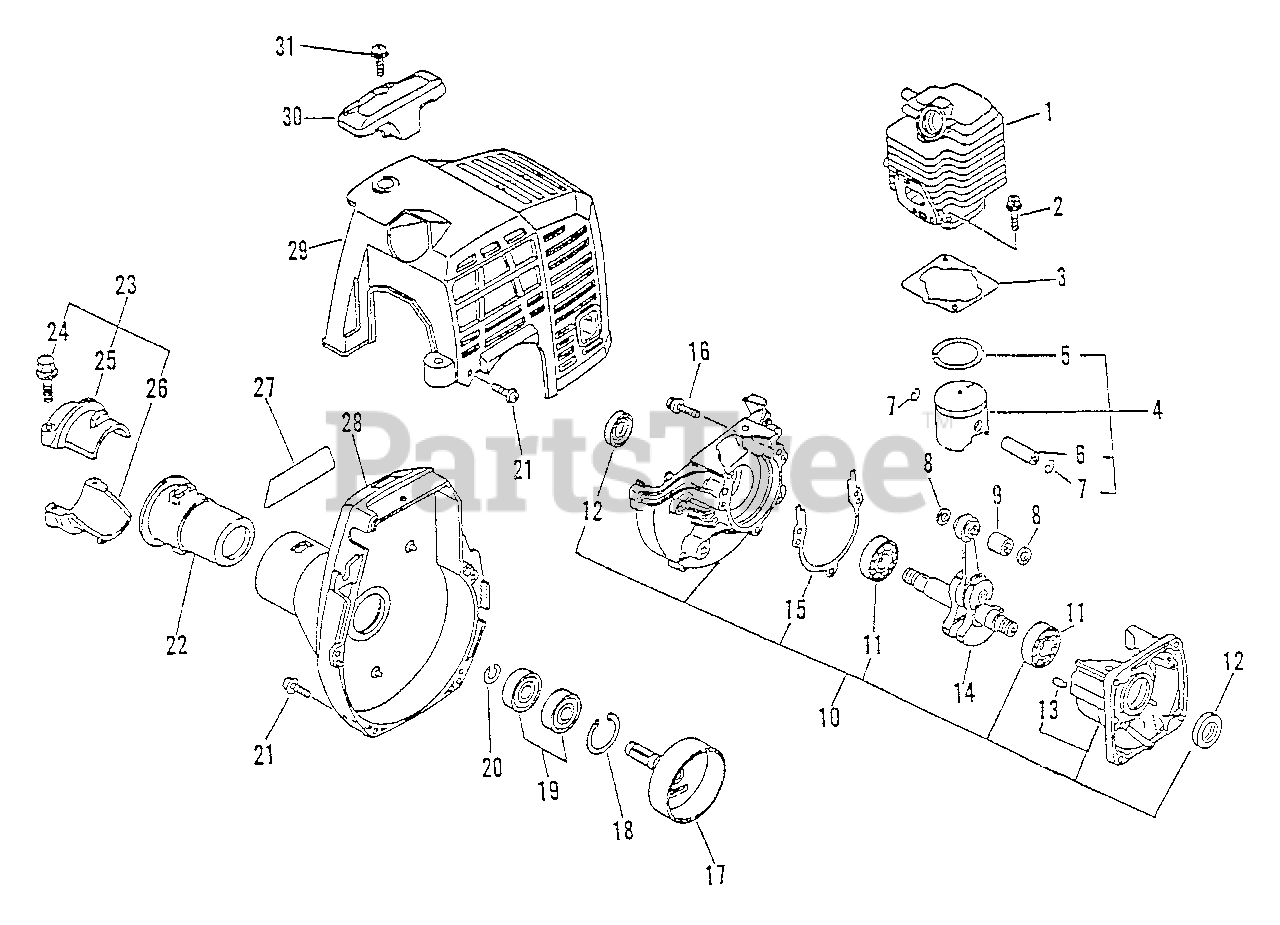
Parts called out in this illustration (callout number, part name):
1	CYLINDER
2	BOLT 5×22
3	GASKET, CYLINDER
4	PISTON KIT
5	RING, PISTON
6	PIN, PISTON 8
7	RING, SNAP
8	WASHER, THRUST
9	BEARING, NEEDLE
10	CRANKCASE KIT
11	BEARING, BALL - 6201 C3
12	SEAL, OIL 12
13	PIN, LOCATING 4
14	CRANKSHAFT ASSY
15	GASKET, CRANKCASE
16	SCREW 5×28
17	DRUM, CLUTCH
18	RING, SNAP 28
19	BEARING, BALL 6001
20	RING, RETAINING - 12
21	BOLT 4×16
23	HOLDER KIT
24	BOLT - 5×25
25	HOLDER, MAIN PIPE - UPPER
27	LABEL, LST-2100
28	FAN CASE ASSY
29	COVER, ENGINE
30	GUARD, TOP
31	SCREW 5×16
